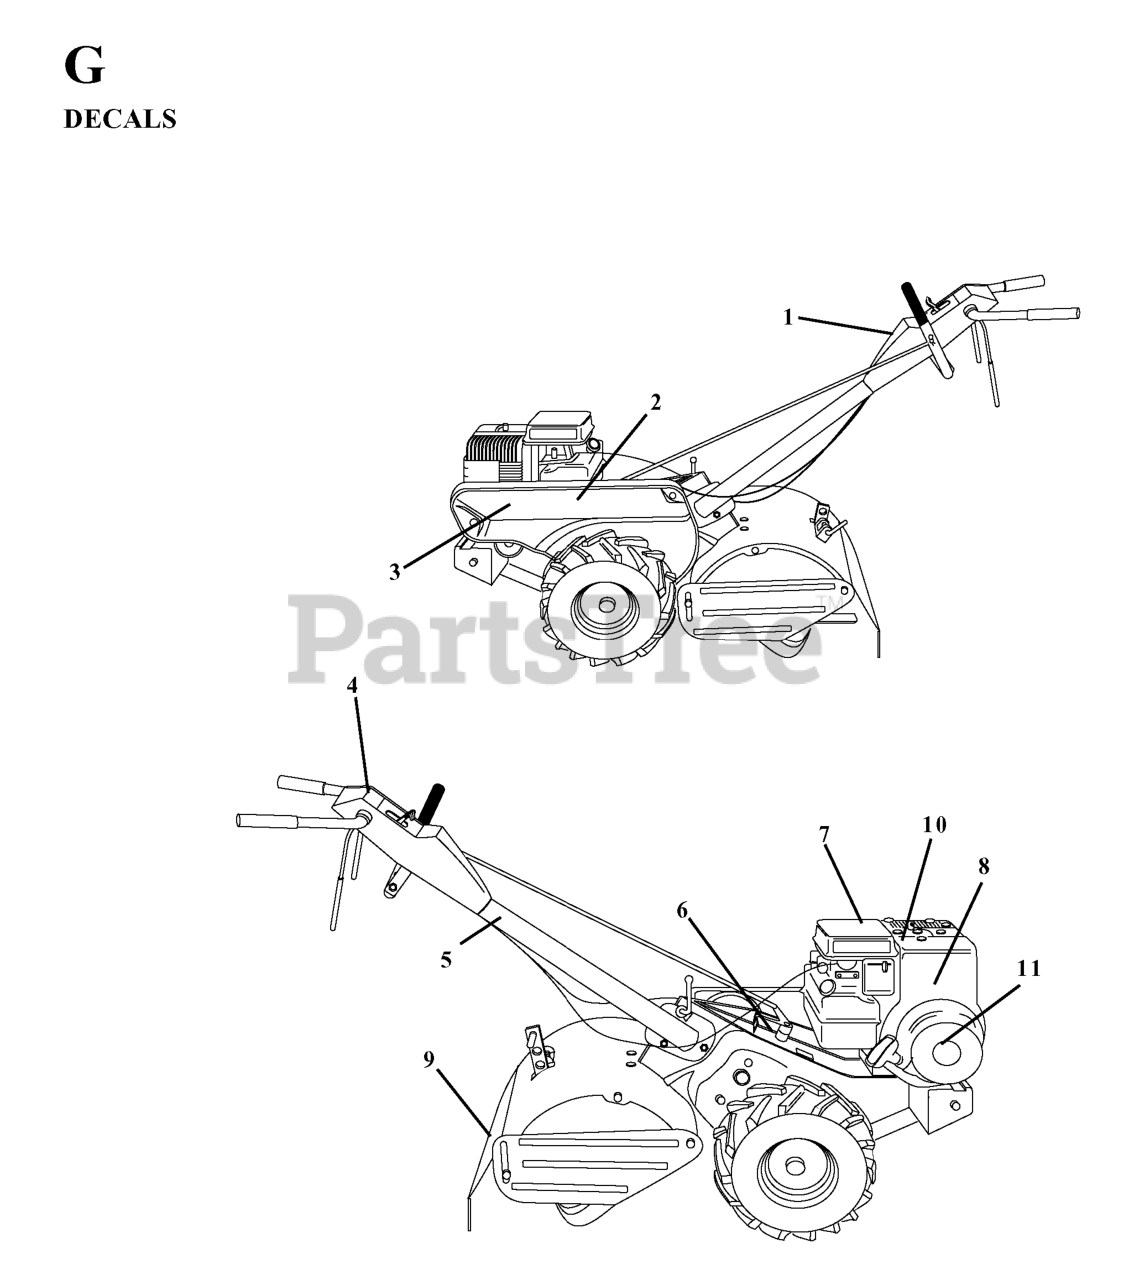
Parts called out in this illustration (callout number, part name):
1	DECAL, LOGO
4	DECAL, LOGO
5	DECAL.PLACEMENT.HAND.SYMBOLS
6	DECAL.SHIFT.INDICATOR.TILLER
8	DECAL, B & S ENGINE
10	DECAL EUROPE STANDARD CE
